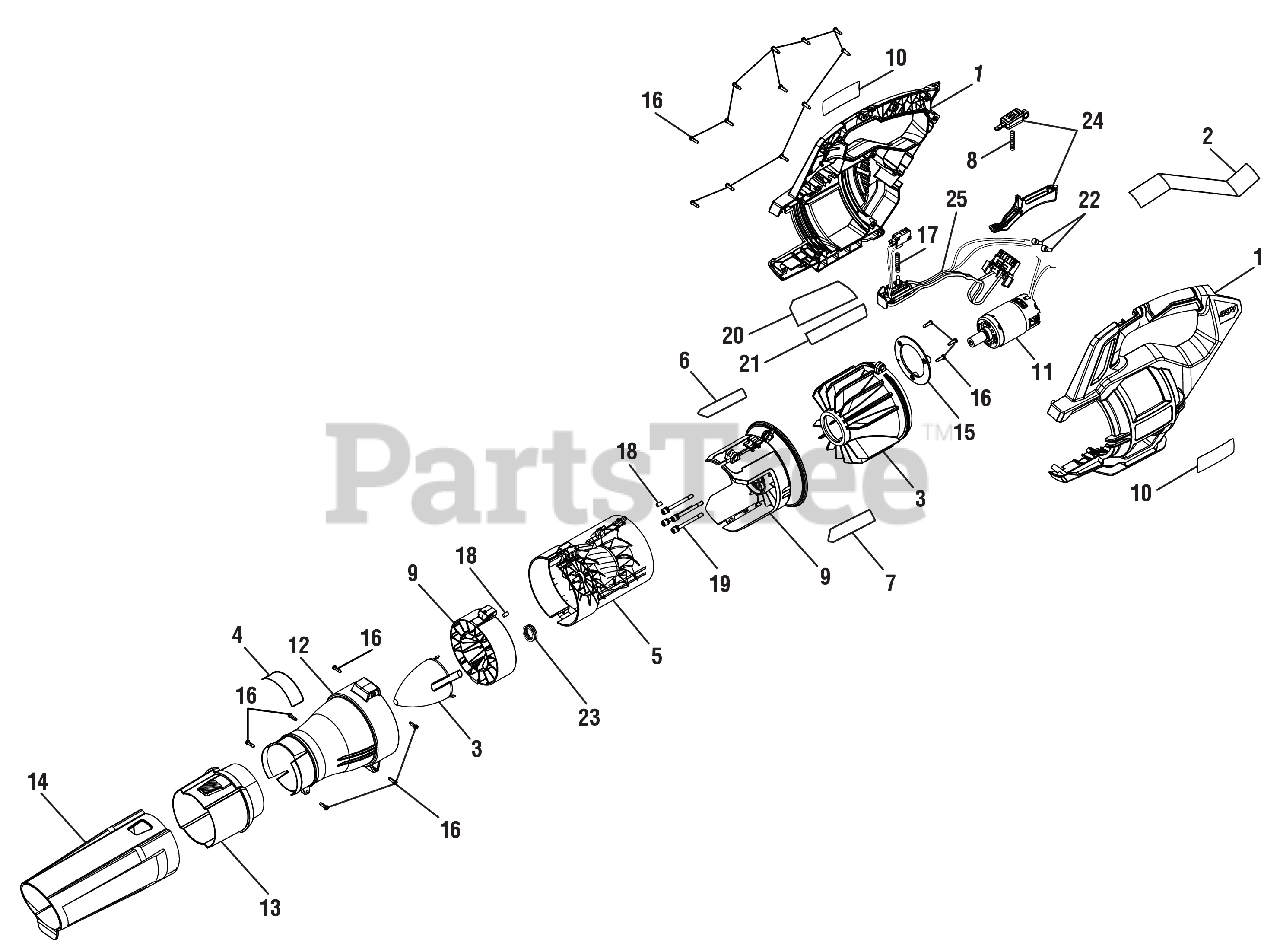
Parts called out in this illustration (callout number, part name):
1	Handle Housing Assembly
2	Warning Icon Label
3	Tail Cone & Intake Housing Assembly
4	Warning Label (English & French)
5	Fan and Guide Vane Assembly
6	Jet Fan Label (Right)
7	Jet Fan Label (Left)
8	Compression Spring
9	Stator & Motor Mounting Housing Assembly
10	Logo Label
11	Motor Assembly
12	Outlet Housing Assembly
13	Tube Connector
14	Blower Tube
15	Baffle Plate
16	Screw (M4 x 14 mm, T15 Torx Pan Hd.))
17	Compression Spring (Trigger)
18	Contact Plate Stopper
19	Screw w/Washer (M5 x 50 mm, Hex Soc. Hd.)
20	Data Label
21	Warning Label (Spanish)
22	Wire Connector (Closed End)
23	Wave Washer
24	Trigger & Turbo Button
25	Contact Plate, Switches & Wiring Harness Assembly
